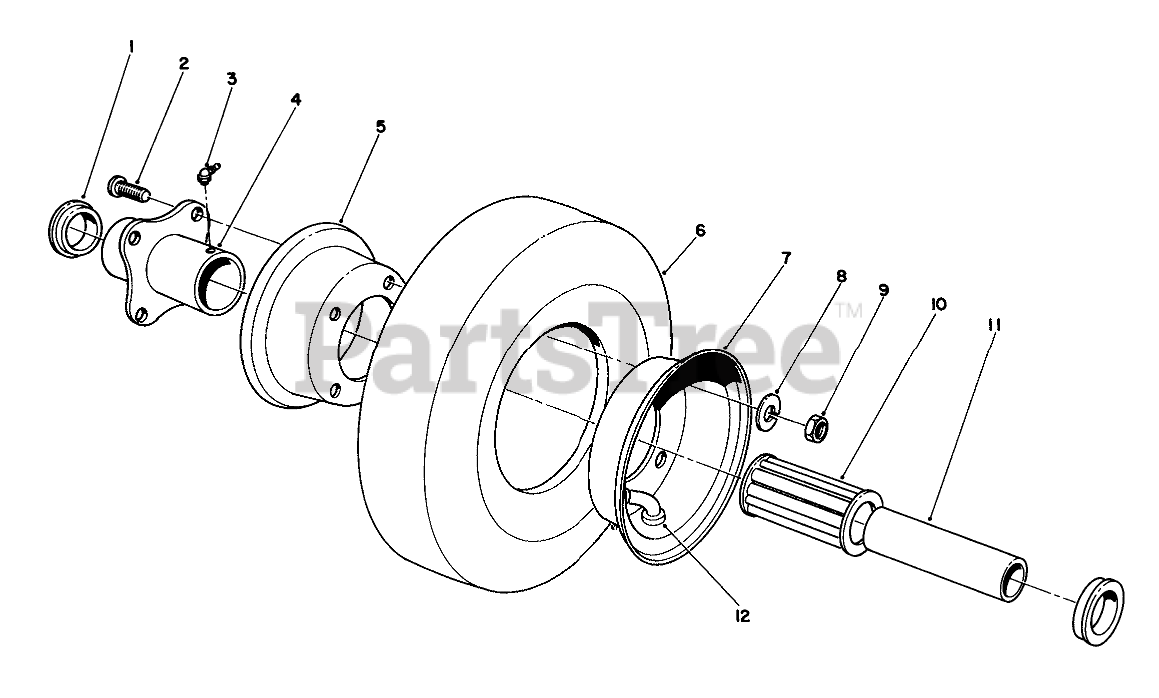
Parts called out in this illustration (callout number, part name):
1	RETAINER
2	WHEEL BOLT
3	FITTING-GREASE
4	HUB-CENTERED
5	WHEEL HALF-FEMALE
6	TIRE-8 Inch (4-PLY)
7	WHEEL HALF-MALE
8	WASHER-LOCK
9	NUT-HEX
10	BEARING-ROLLER
11	Bushing-Spanner
